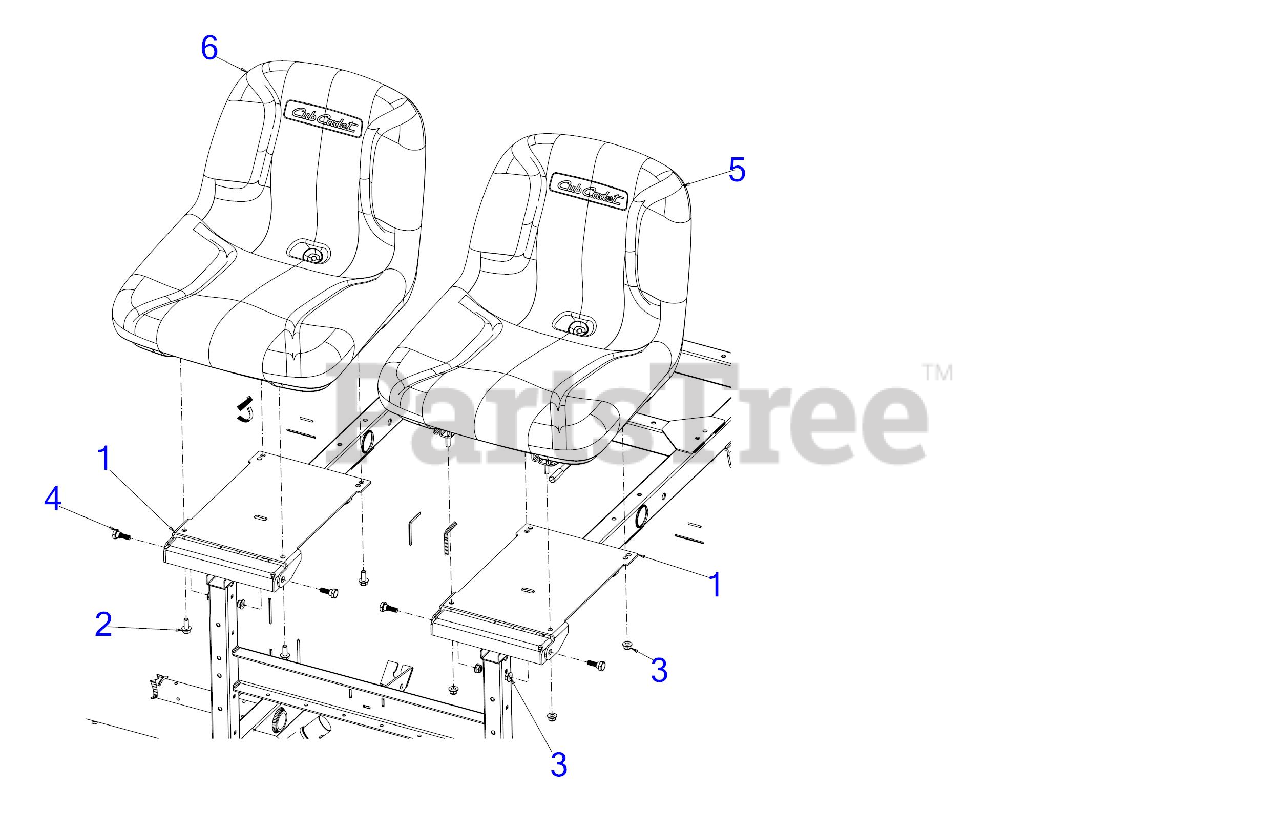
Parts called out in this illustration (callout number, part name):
1	SEAT MOUNTING BRACKET (POWDER BLACK)
2	SCREW 5/16-18
3	FLANGE LOCK NUT 5/16-18
4	SHOULDER SCREW .437
5	HIGH BACK SEAT (DRIVER)
6	HIGH BACK SEAT (PASSANGER)
